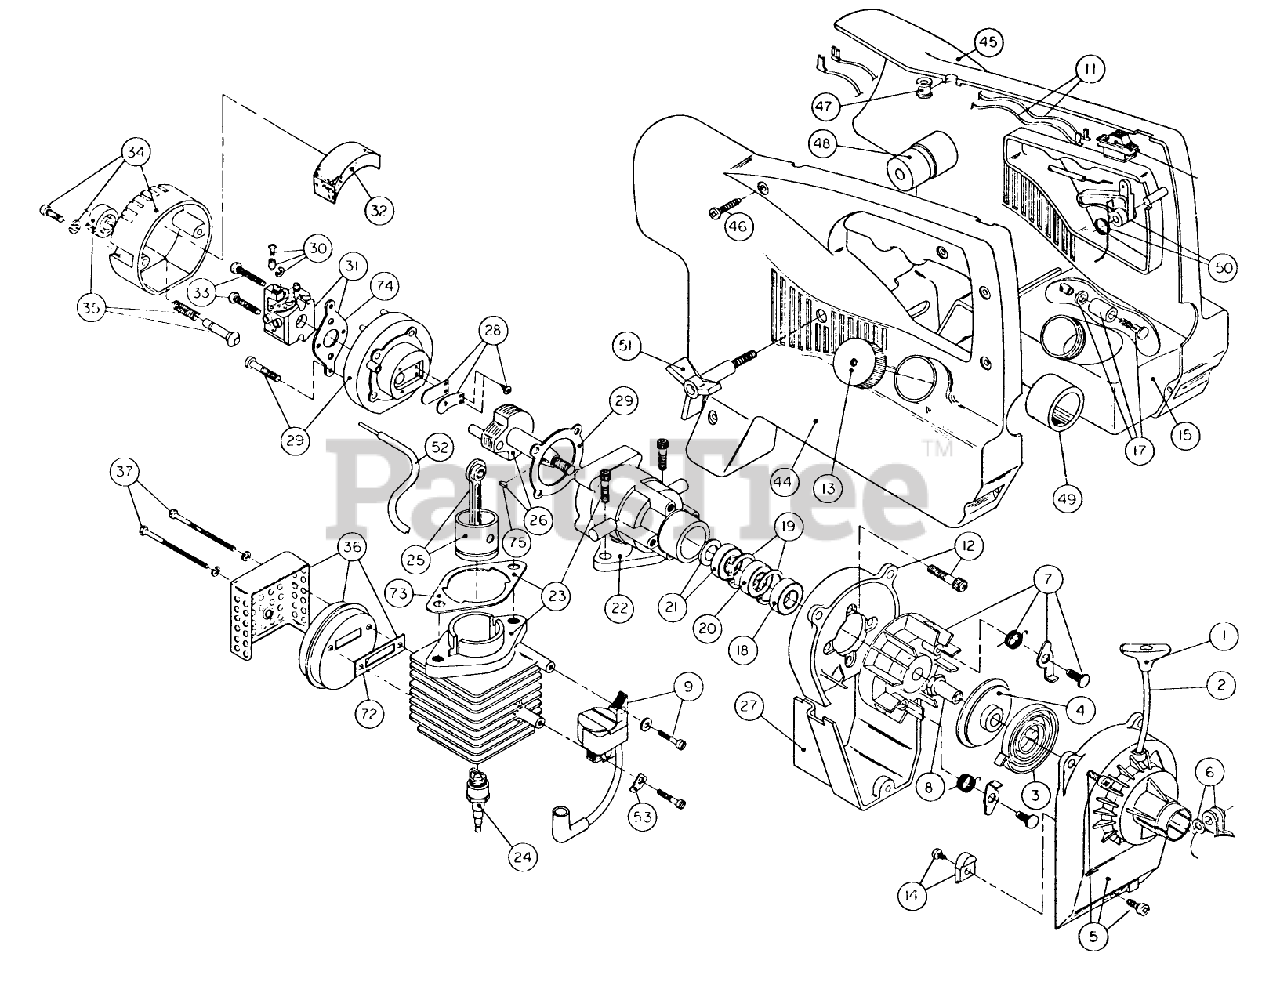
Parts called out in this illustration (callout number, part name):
2	Rope
8	SQUARE DRIVE NUT
9	Module Assembly
11	Wire Leads Assembly
12	Float Shaft
18	OUTER BEARING
20	SEAL
21	CONTROL CABLE WES
24	SPARK PLUG
30	THROTTLE ADJ ASM
37	MUFFLER MOUNTING BOLTS
74	CARB.GASKET
75	FLYWHEEL KEY (10-PK)
